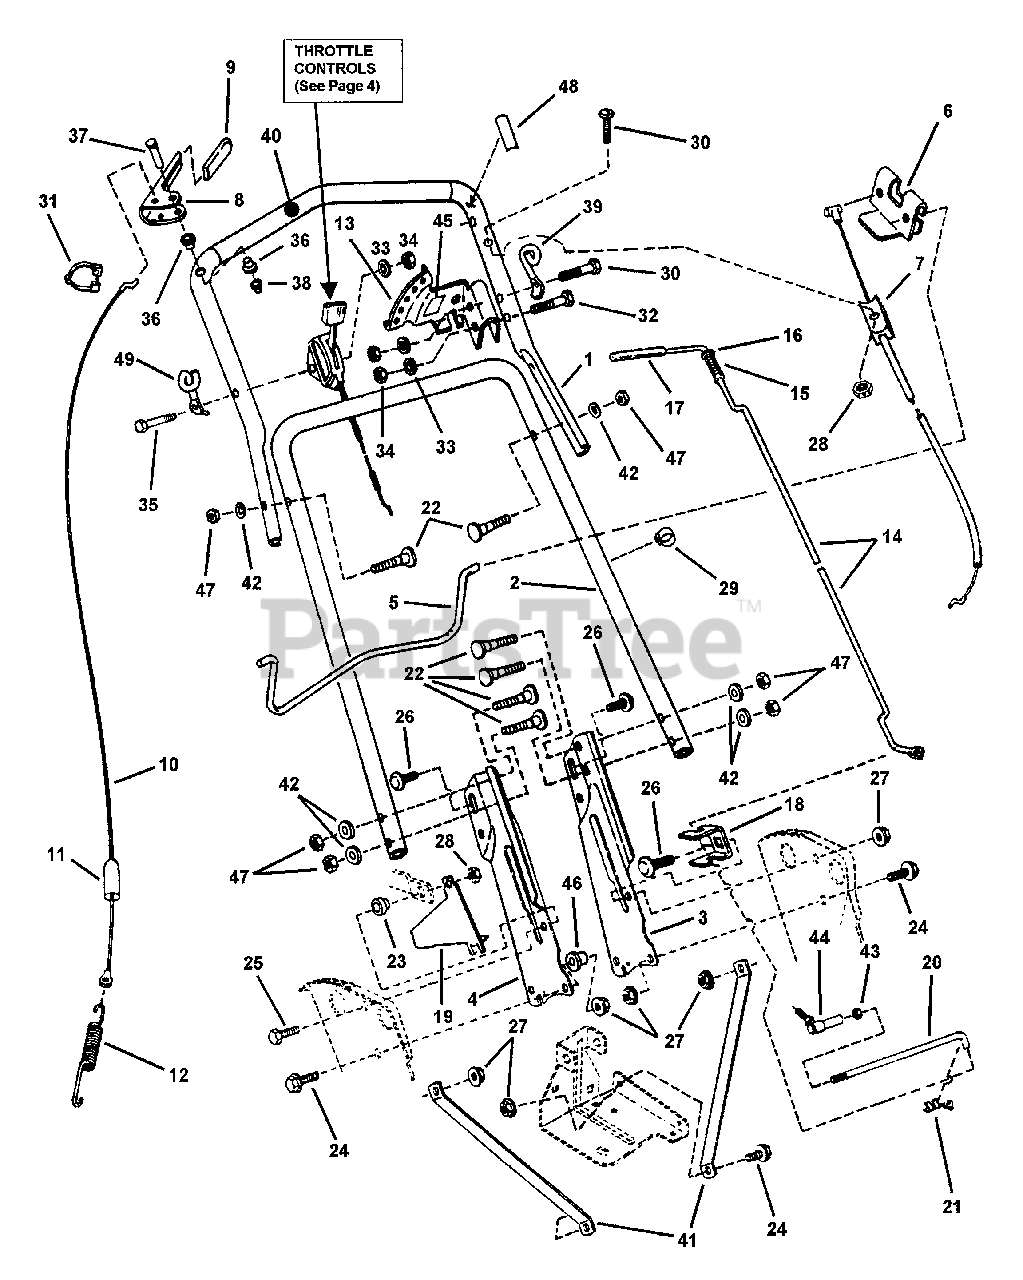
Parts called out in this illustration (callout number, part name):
1	HANDLE, Upper
2	HANDLE, Middle
3	HANDLE, Lower Right Hand
4	HANDLE, Lower Left Hand
5	CONTROL, Blade (16.6" Wide)
6	CLIP, Blade Control
7	CABLE, Blade Control (47.56/5.34 length)
7	CABLE, Blade Control (57.50/5.52 length, snap-in)
7	CABLE, Blade Control (46.12/5.38 length)
8	HANDLE, Wheel Drive
9	GRIP, Wheel Drive Handle
10	CABLE, Clutch Pull (Z-Bend) (41.44" length)
11	COVER, Vinyl
12	SPRING, Clutch
13	SECTOR, Speed
14	LEVER, Speed Control
15	SPRING, Speed Control
16	WASHER, 3/8" Flat
17	GRIP, Speed Control Handle
18	ANCHOR, Speed Control
19	GUIDE, Lower V-Belt
20	ROD, Transfer
21	CLIP, Transfer Rod
22	BOLT, 5/16-18 x 1-1/2" Curved Head
23	BUSHING, Differential
24	BOLT, 5/16-18 x 3/4" Hex Flange Lock Gr. 5
25	SCREW, 5/16-24 x 1" Hex Cap Grade 5
26	BOLT, 5-16-18 x 5/8" Carriage Grade 5
27	NUT, 5/16-18 Hex Flange Lock Grade 5
28	NUT, 5/16-24 Hex Center Lock Grade B
29	CLIP, Wiring Harness
30	SCREW, 1/4-20 x 1-3/4" Hex Cap Grade 5
31	CLAMP, 7/8" Double Cable
32	SCREW, 1/4-20 x 1-1/2" Hex Cap Grade 5
33	WASHER, 1/4 Internal Tooth Lock
34	NUT, 1/4-20 Hex
35	SCREW, 1/4-20 x 2" Hex Cap Grade 5
36	BUSHING
37	PIN, Clutch Handle
38	NUT, Push (for handle pin)
39	GUIDE, Rope (Left Hand)
40	GRIP, Foam
41	STRAP, Handle
42	WASHER, 5/16 Internal Tooth Lock
43	NUT, 1/4-28 Hex, Grade 5
44	JOINT, Ball
45	DECAL, Speed Selector
46	NUT, 5/16-18 Tee
47	NUT, 5/16-18 Hex Grade 5
48	DECAL, Blade Control
49	GUIDE, Rope (Right Hand)
